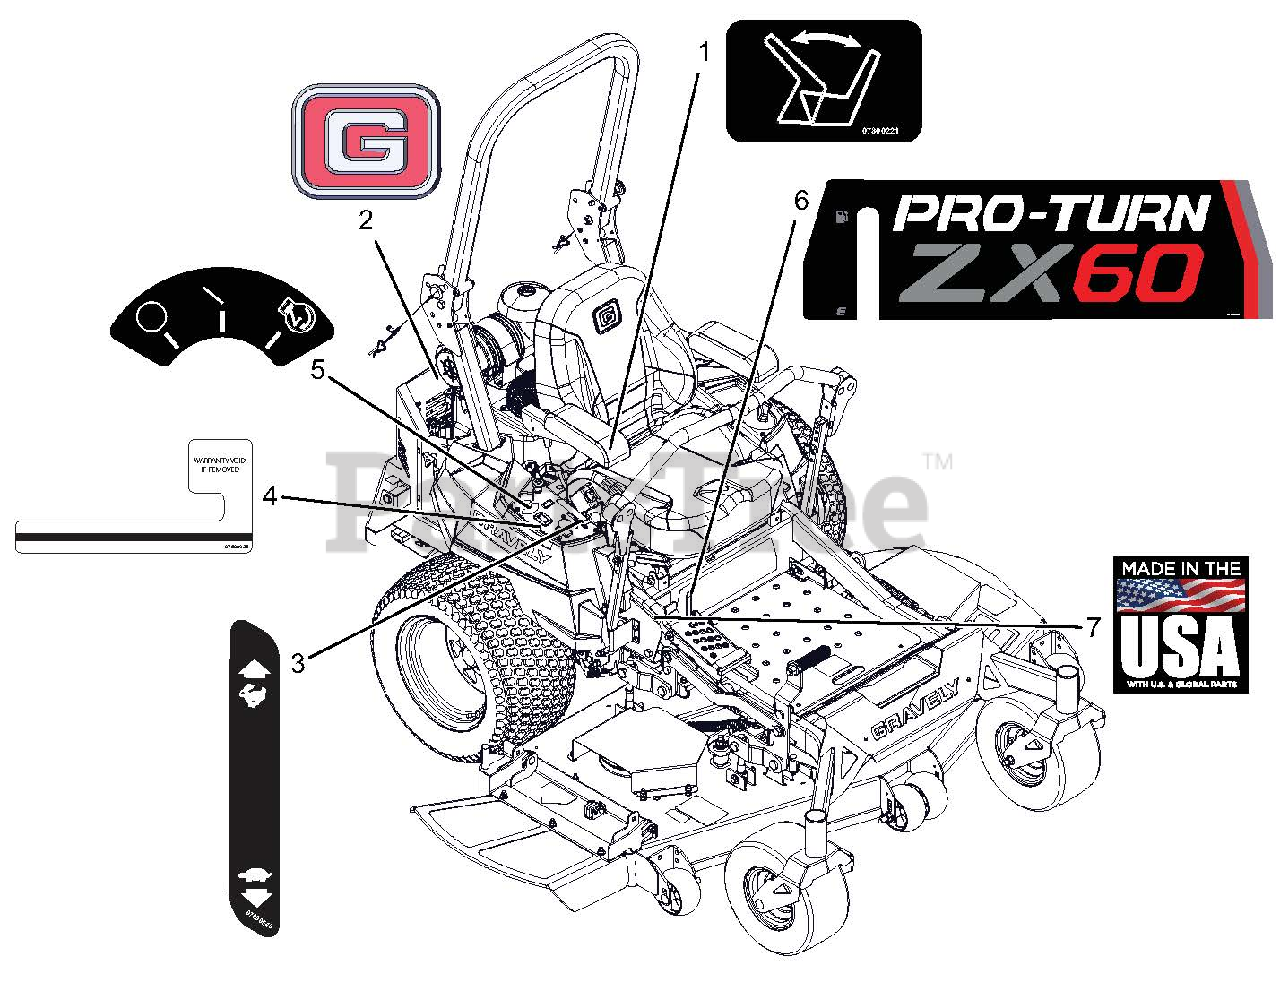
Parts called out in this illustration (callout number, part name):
1	DECAL - SEAT RELEASE
2	DECAL, GRAVELY BRAND
3	DECAL, DASH DECAL
4	DECAL,HOURMETER - SECURITY
5	DECAL, KEYSWITCH
6	DECAL, PROTURN ZX 60
7	DECAL, MADE IN USA
